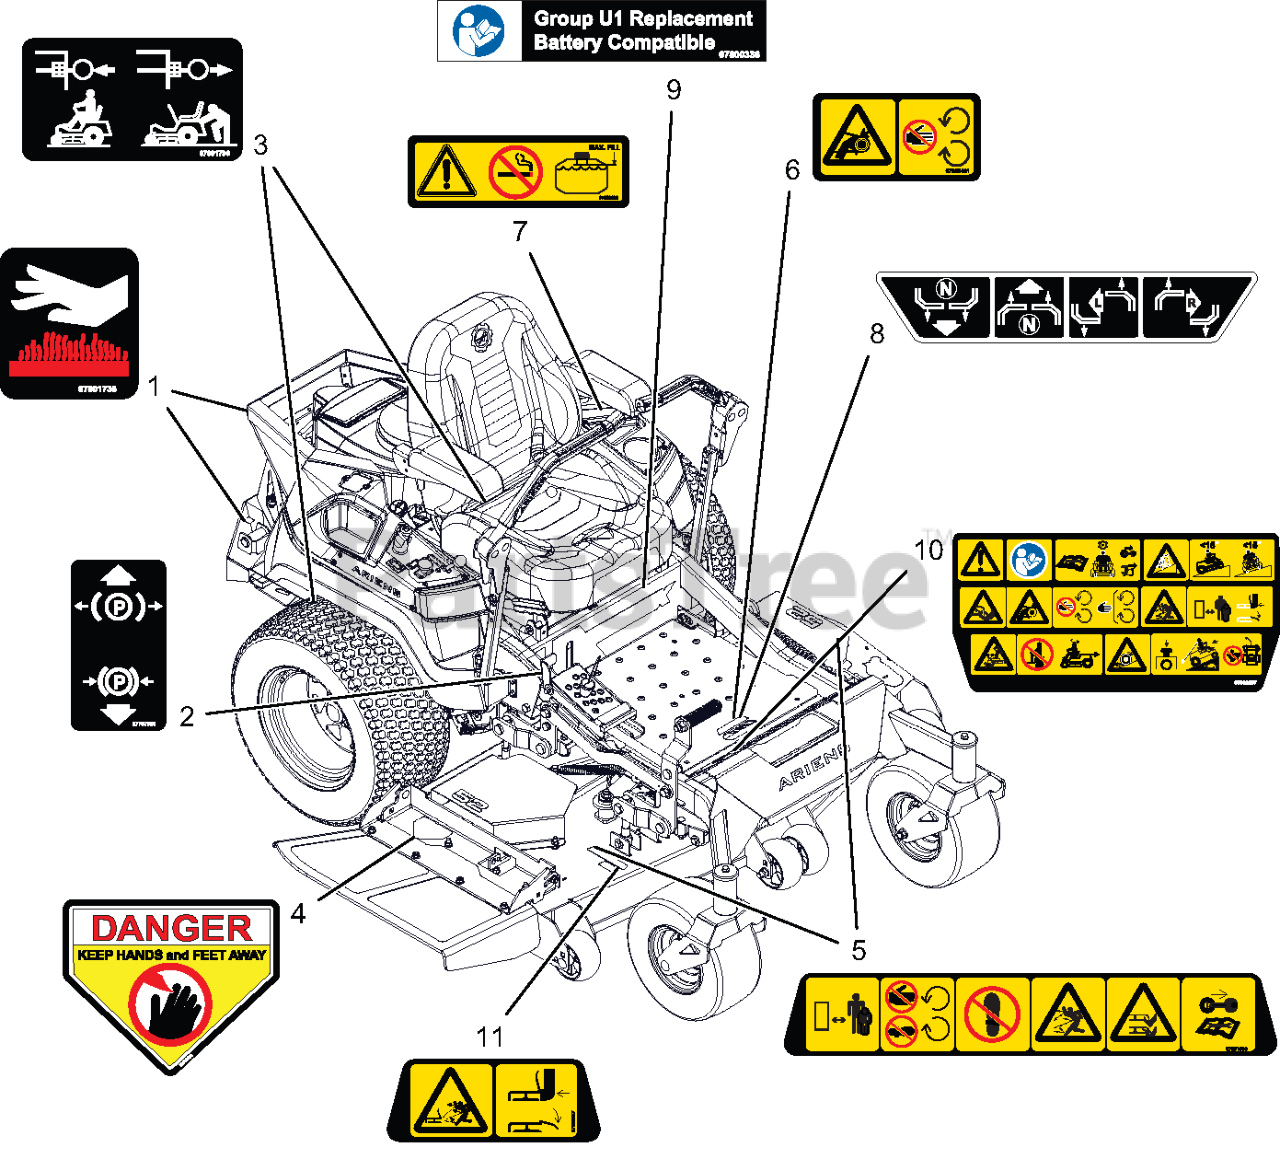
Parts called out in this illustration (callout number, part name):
1	DECAL- HOT SURFACE
2	DECAL, PARKING BRAKE LEVER
3	DECAL- TRANSAXLE DISCONNECT
4	DECAL, DANGER
5	DECAL- SAFETY - MOWER DECK
6	DECAL, SAFETY - GUARDING
7	DECAL, FUEL WARNING
8	DECAL, INSTRUCTION - STEERING
9	DECAL, U1 BATTERY REPLACEMENT
10	DECAL, MAIN SAFETY
11	DECAL- SAFETY - DECK GUARDING
